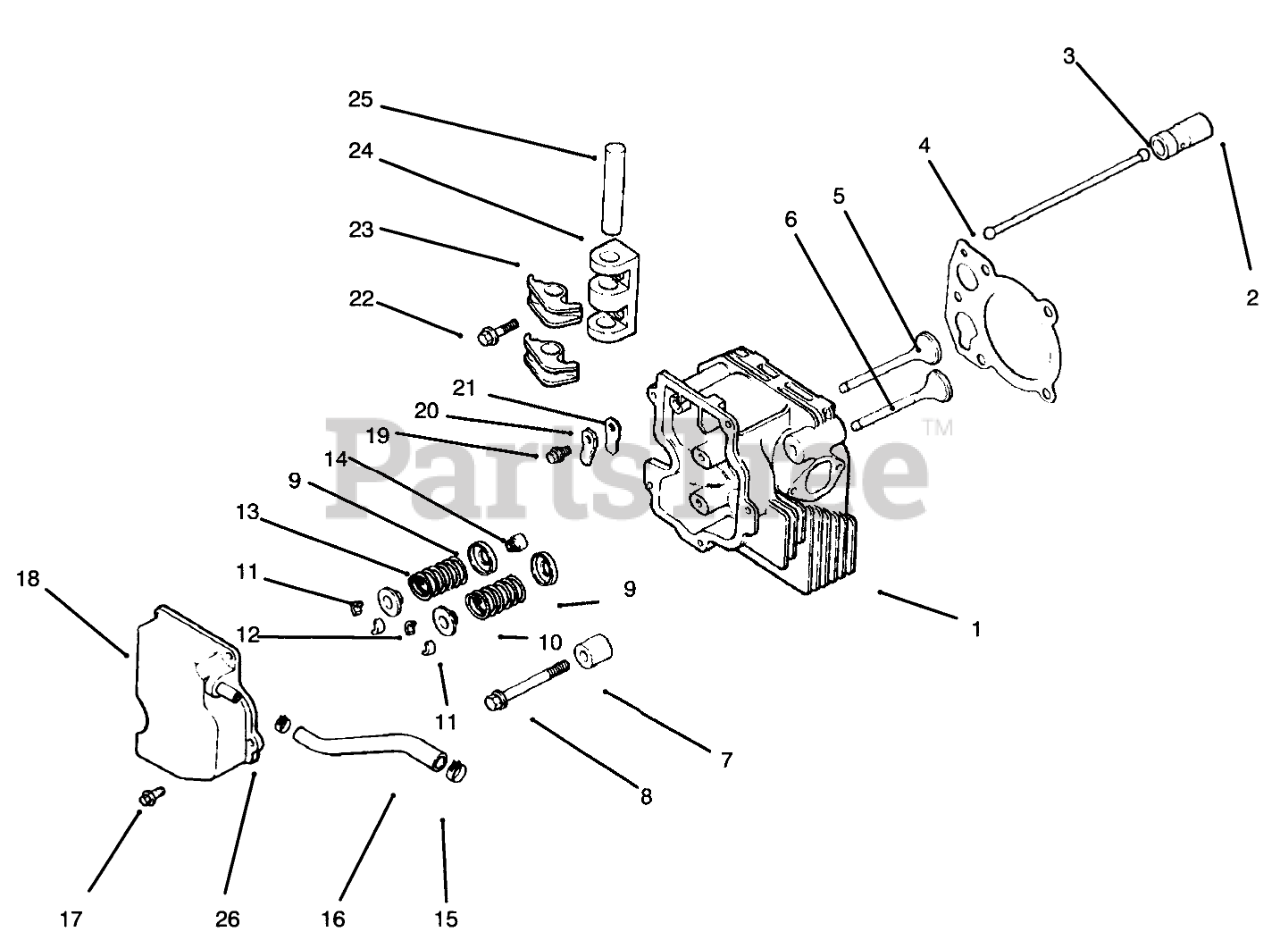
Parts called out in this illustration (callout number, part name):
1	Cylinder Head
2	Lifter-Valve
3	Rod-Push
4	Gasket-Cylinder Head
5	Valve-Intake STD
6	Valve-Exhaust STD
7	Spacer-Head Bolt
8	Screw-Cylinder Head
9	Retainer-Spring
10	Spring-Valve Intake
11	Cap-Valve Spring
12	Kit-Retainer
13	Spring-Valve, Intake
14	Seal
15	Clamp
16	Hose-Breather
17	Screw
18	Cover-Valve
20	Retainer-Reed
22	Screw
23	Arm-Rocker
24	Bridge-Rocker Arm
25	Shaft-Rocker Arm
26	Clamp-Hose
